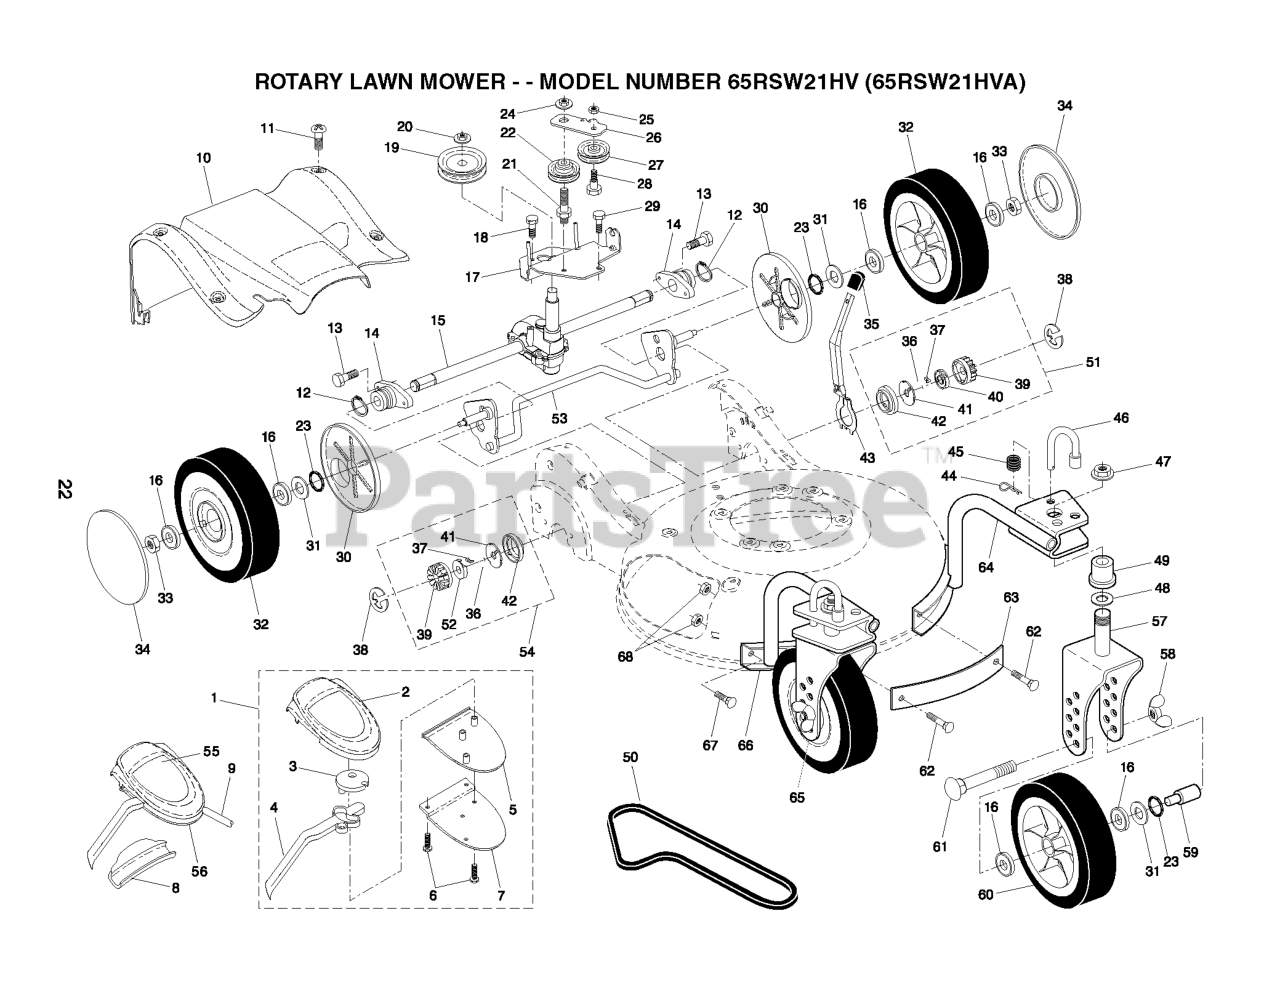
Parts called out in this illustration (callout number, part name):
1	EZ WALK CONTROL
2	COVER, DRIVE CONTROL, TOP
3	PULLEY.CAM.DRIVE.CONTROL.HV
4	LEVER, DRIVE CONTROL
5	COVER, DRIVE CONTROL BOTTOM
6	SCREW, PHILLIPS HEAD 10 X 5/8
7	BRACKET, DRIVE CONTROL
8	EZ WALK SNAP COVER PLATE
9	CABLE, DRIVE CONTROL
10	COVER, REAR DRIVE
11	SCREW
12	RETAINING RING (2 2)(3 2)
13	RP SCREW
14	BEARING.SUPPORT.ASSEM
15	TRANSMISSION.ASM.RGD.EZ.21
16	BEARING.8".WHEEL
17	BRACKET, TRANSMISSION
18	Screw, Hex Washer Head #10-24 x .668
19	PULLEY HALVES
20	FLANGED LOCKNUT 3/8-16 ZINC
22	PULLEY ASSY
23	O-RING
24	NUT
25	NUT.CENTERLOCK.5/16-
26	BRACKET
27	IDLER PULLEY
28	SHOULDER BOLT
29	SCREW 14-20 X 5/8
30	DUST COVER, WHEEL
31	WASHER.FLAT.1/2
32	WHEEL 9X2.25
33	HEX FLANGE LOCKNT
34	RB HUBCAP.3-SPOKE.SILVER
35	KNOB.SELECTOR.SPRG.H-GRY (2 2)
36	SPRING, TORSION
37	PAWL.DRIVE.21.EZ-WALK
38	E-RING 7/16 RE
39	GEAR, PINION
40	RETAINER.DRIVE.21.EZ-WALK.LT
41	DISC.DRIVE.21.EZ-WALK
42	SEAL.PINION
43	LEVER, SELECTOR
48	WASHER STEEL
49	BUSHING
50	BELT.DRIVE.EZ.WALK.HI-VAC
51	PINION ASSY, LH
52	RETAINER, DRIVE, RH
53	REAR AXLE ASSY.
54	PINION ASSY, RH
56	DECAL
57	BRACKET, CASTER
58	NUT.WING.5/16-18.YELLOW
60	WHEEL ASSY, FRONT 9X2
61	CARRIAGE BOLT
63	STRAP, FRONT
64	SUPPORT TUBE ASSY, LH BLK
65	BRACKET CASTER WHEEL, RH
66	SUPPORT TUBE ASSY, RH
68	NUT
